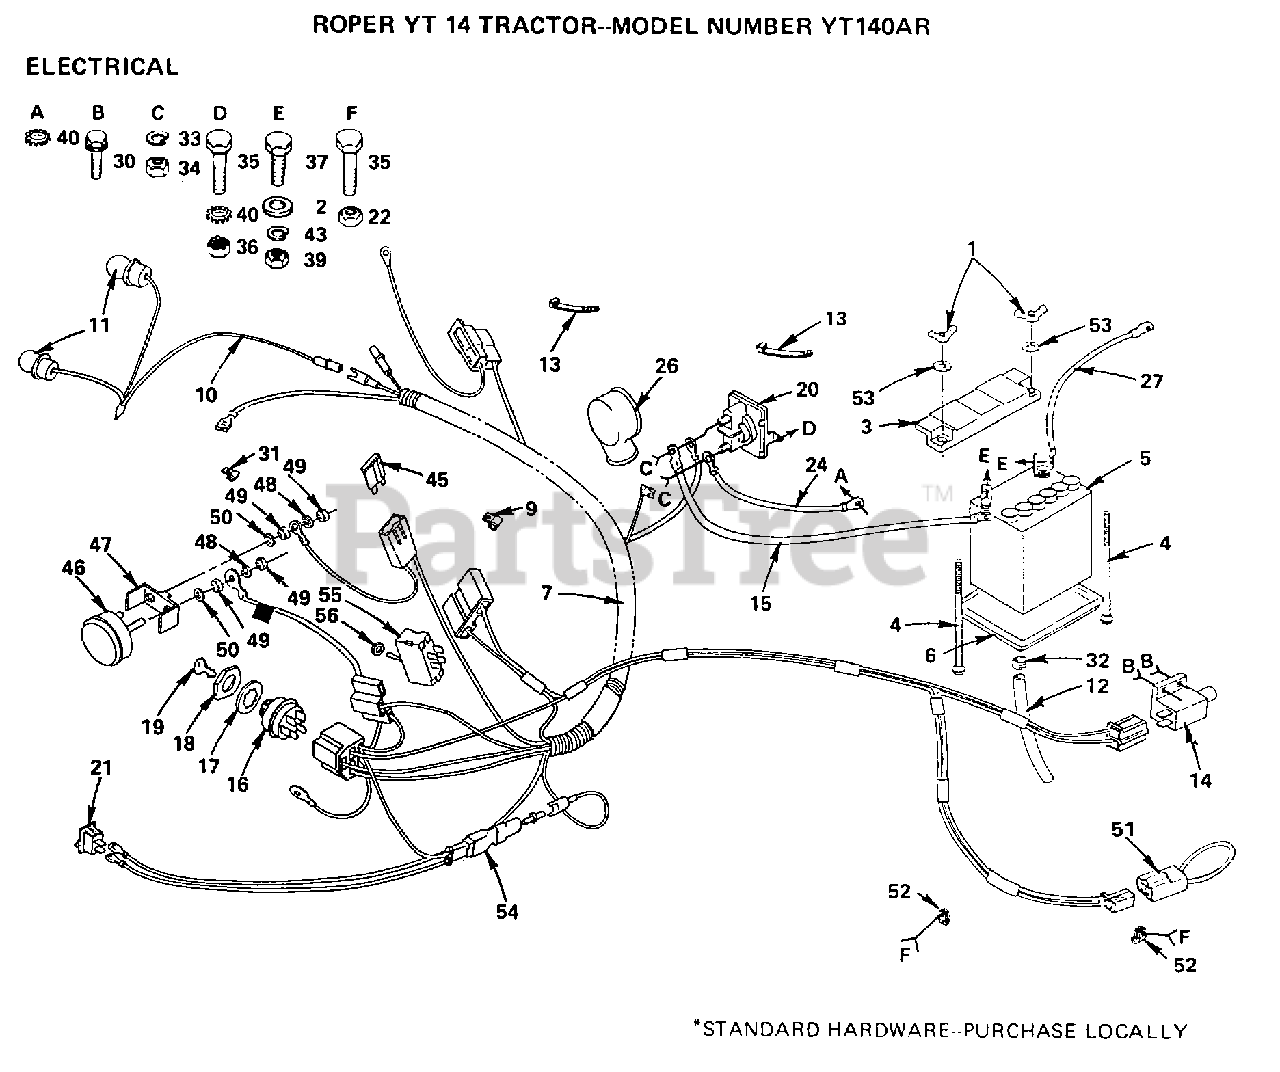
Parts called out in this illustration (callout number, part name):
2	WASHER
4	BOLT
6	"TRAY T, BATTERY"
10	HARNESS T
13	WIRE TIE
14	SWITCH-INTER. GT
15	"CABLE T, BATTERY"
17	LOCKWASHER
18	CONDUIT NUT L
27	CABLE ASSY LT
31	CLIP T
34	NUT
35	BOLT
36	NUT
37	BOLT LT
43	LOCKWASHER
45	FUSE HYT
46	AMMETER T
52	CLIPT
53	LOCKWASHER GT
55	SWITCH.PTO.T
56	HEX NUT T
